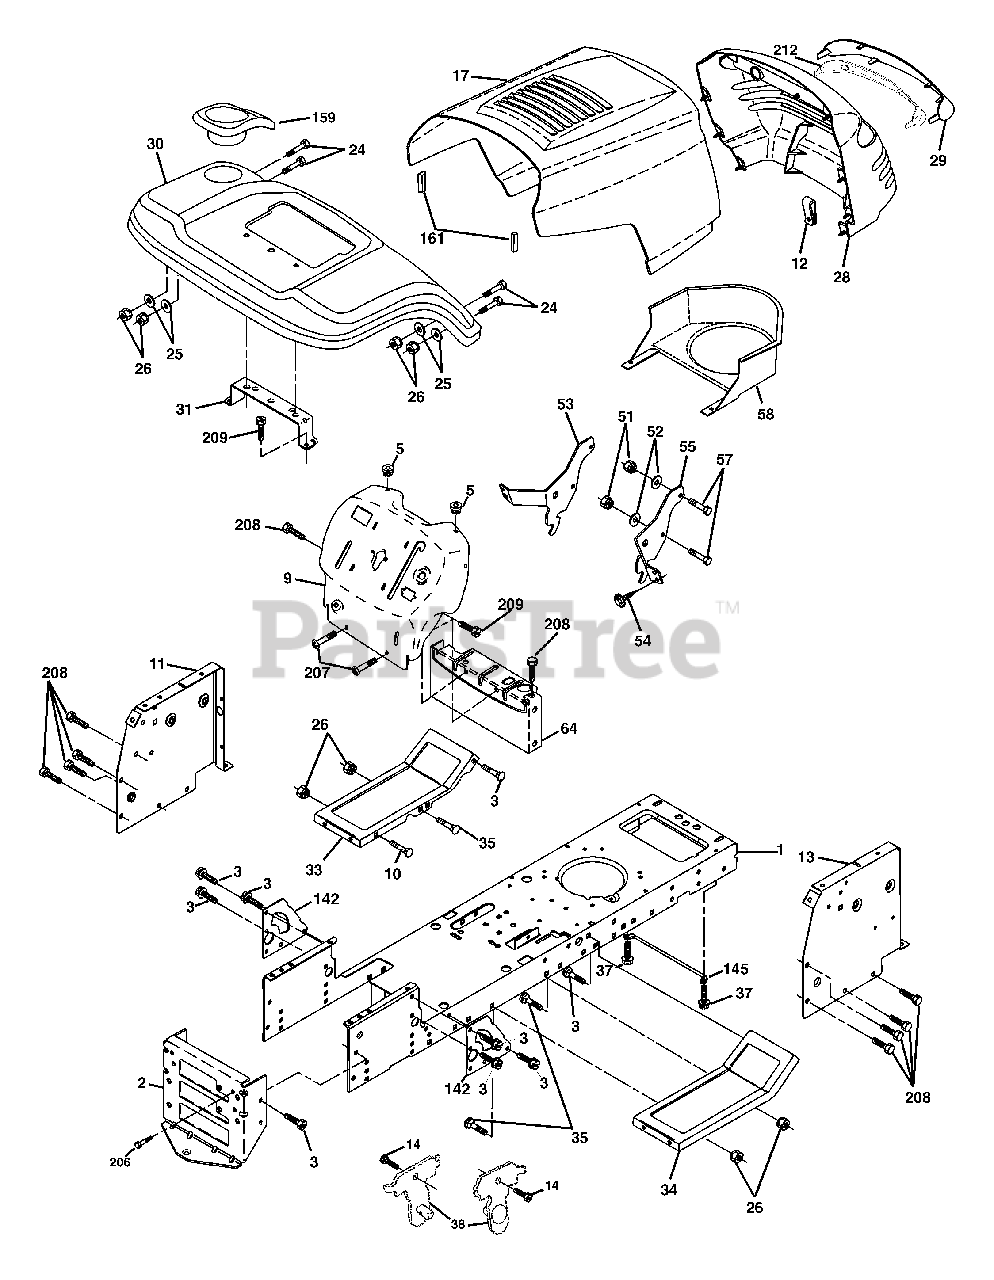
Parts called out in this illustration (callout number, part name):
1	Chassis
2	Drawbar
3	Screw 3/8-16 x 3/4
5	Bumper Hood/Dash
9	Dash
10	Bolt Rd Hd Sqnk. 3/8-16 Unc x 1
11	Panel Asm. Dash Lh
12	Clip Tinnerman Grile P/L
13	Panel Dash Rh
14	Screw Thdrol 3/8-16 x 1/2
17	Hood
18	Bumper Hood
24	Bolt Fin Hex 3/8-16 Unc x 1 Gr. 5
25	Washer 13/32 x 13/16 x 12 Ga.
26	Nut Lock Hex w/Insert 3/8-16 UNC
28	Grill/Lens Asm
29	Lens Grille
30	Fender Asm
31	Bracket Fender
33	Footrest LH
34	Footrest RH
35	Bolt Rd Hd Sht. Sqnk. 3/8-16 x 3/4
37	Screw Thdrol 5/16-18 x 1/2 Tyt
38	Bracket Asm. Pivot Mower Rear
51	Nut Lock Hex W/Ins. 1/4-20
52	Washer 9/32 x 7/8 x 16 Ga.
53	Bracket Grille LH
54	Screw Hex Wshd 8-18 x 7/8
55	Bracket, Grille RH
57	Bolt Fin Hex 1/4-20 x .75
58	Air Duct Private Label
64	Dash Lower
142	Plate Reinforcement
145	Rod Pivot Chassis/Hood
159	Cupholder
206	Bolt shoulder 5/16-18
207	Screw Thdrol 5/16-18 x 1/2
208	Screw Thdrol 3/8-16 x 1/2
209	Screw 3/8-16 x 3/4
212	Insert Lens Reflector
